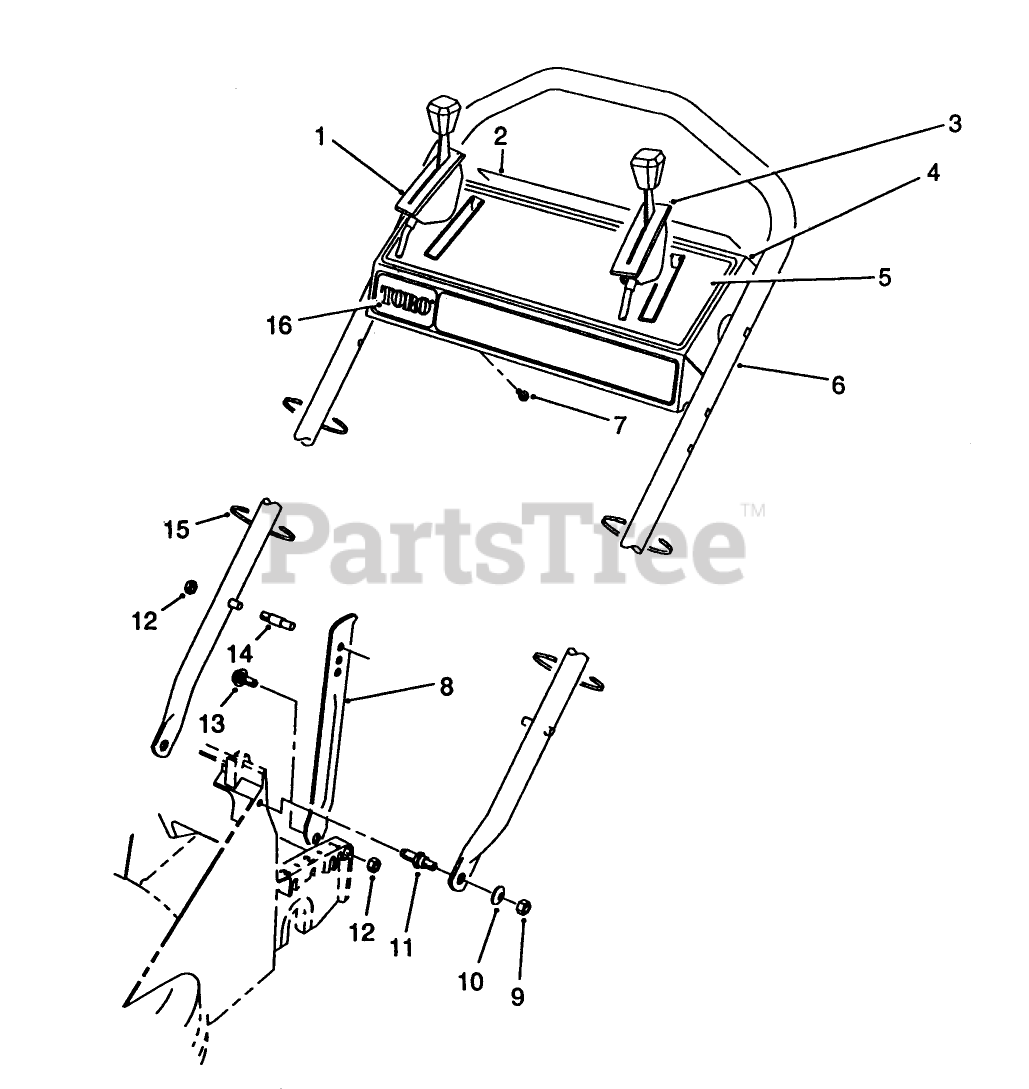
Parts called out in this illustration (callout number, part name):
1	GROUND SPEED CONTROL
2	DECAL-PANEL, DANGER
7	SCREW-HWHTF
9	NUT-LOCK, NI
10	WASHER-PLAIN
12	NUT-LOCK, NI
14	HANDLE PIN
15	TIE-CABLE
